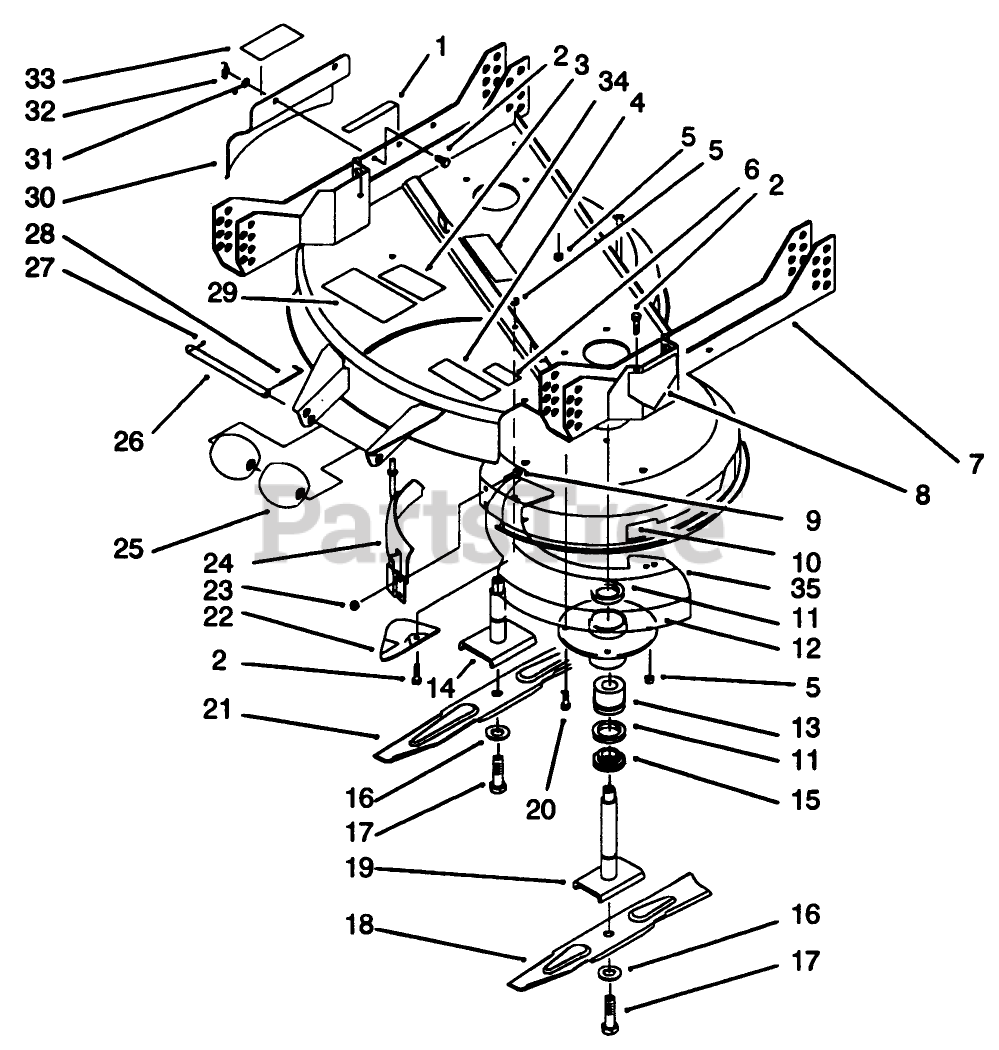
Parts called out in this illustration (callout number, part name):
1	DECAL-DANGER, DEFLECTOR
2	SCREW-HH
3	DECAL-TORQUE
4	DECAL - DISCHARGE DOOR
5	NUT-LOCK, NI
6	Decal
7	Deck Support (Incl. Ref. #3, 4, 6, 8, & 29)
8	DECAL-DANGER
9	SCREW-CARRIAGE
10	DECAL - 37"
11	SEAL-OIL
12	SPINDLE HOUSING
13	BEARING ASM
14	SHAFT-SPINDLE
15	SPACER
16	WASHER-LOCK
17	SCREW-BLADE
18	Blade-17"
19	SHAFT-SPINDLE
20	SCREW-HH
21	Blade-21"
22	PLATE-KICKER
23	NUT-KEPS
24	Cover-Front
25	ROLLER
26	SHAFT-ROLLER
27	PIN-COTTER
28	PIN-SPECIAL
29	DECAL-DANGER, THROWN OBJECT
30	Cover-Discharge
31	WASHER-LOCK
32	NUT-WING
33	DECAL - DANGER
34	DECAL-DANGER
35	Insert-Deck
